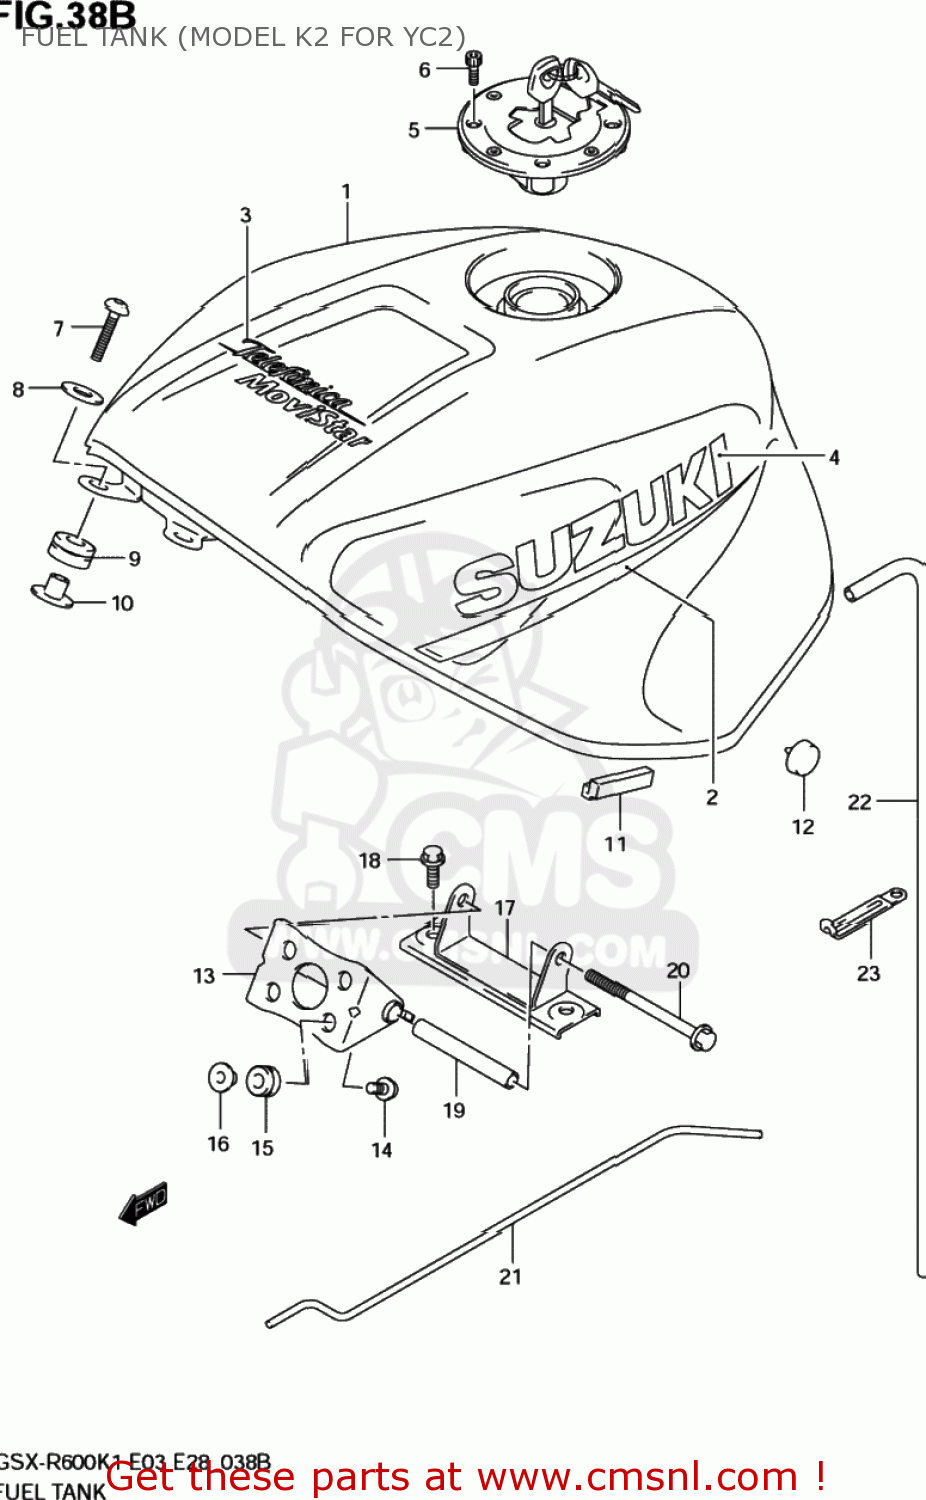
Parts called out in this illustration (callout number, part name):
1	TANK ASSY,FUEL(BLUE)
2	TAPE SET,FUEL TANK
3	EMBLEM,MOVISTAR
4	EMBLEM(WHITE)
5	CAP SET,FUEL TANK
6	BOLT(5X20)
7	SCREW(6X25)
8	WASHER(6.5X22X1.6)
9	CUSHION,FUEL TANK FR
10	SPACER,FUEL TANK FR
11	CUSHION,FUEL TANK SIDE
12	CUSHION,FUEL TANK SIDE NO.2
13	BRACKET,FUEL TANK NO.1
14	BOLT(6X20)
15	CUSHION
16	WASHER
17	BRACKET,FUEL TANK NO.2
18	BOLT
19	SPACER,FUEL TANK RR
20	BOLT
21	STAY,FUEL TANK
22	HOSE,FUEL TANK WATER DRAIN
23	CLAMP(L:65)
